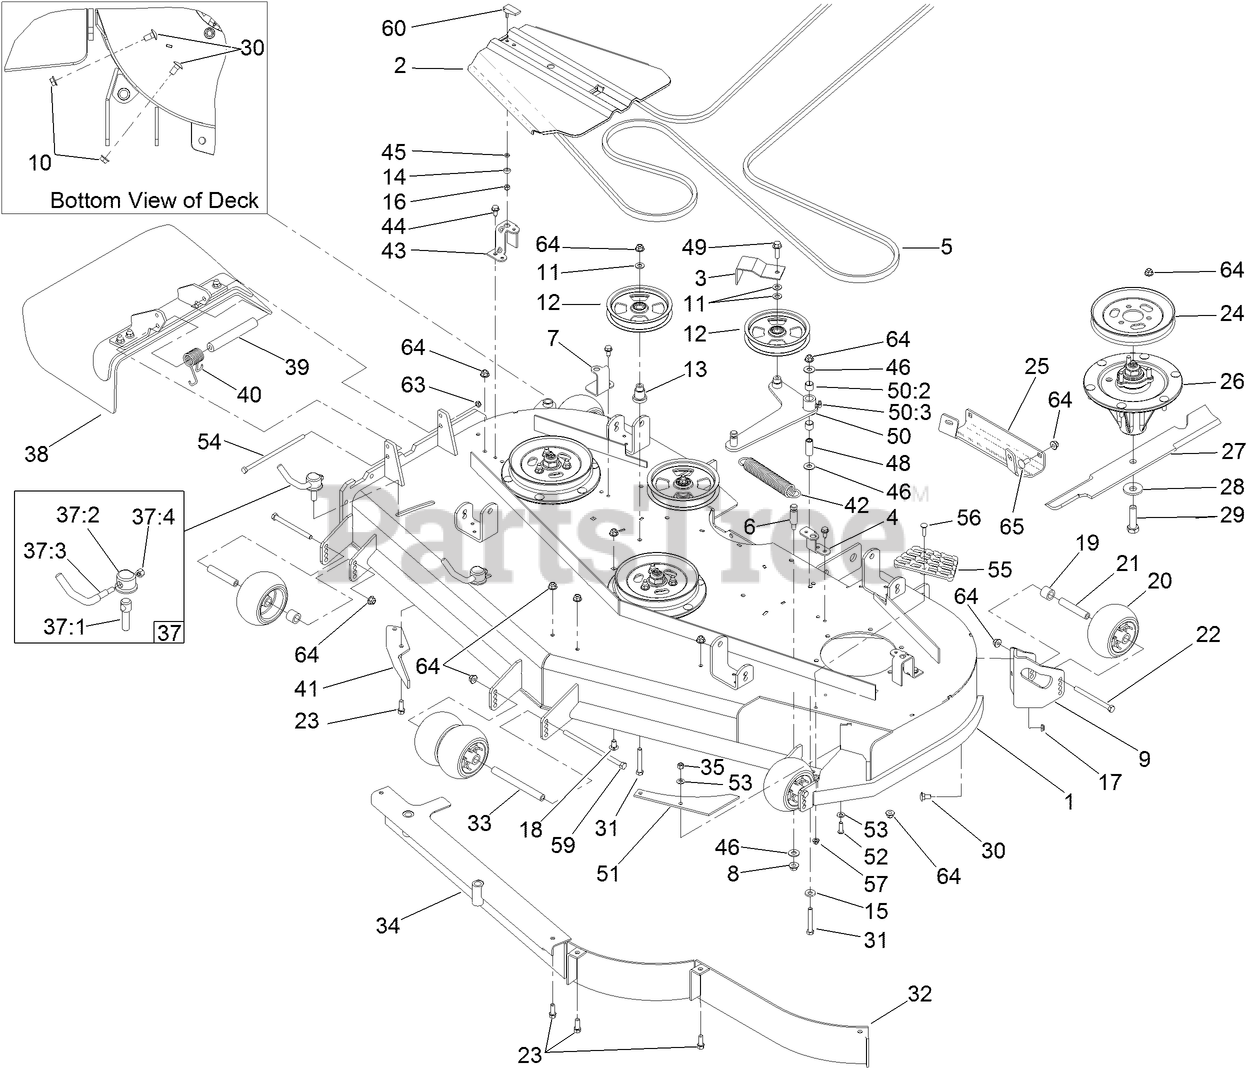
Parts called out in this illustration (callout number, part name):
1	DECK DECAL ASM
2	COVER-BELT
3	GUIDE-BELT
4	BRACKET-COVER, TALL
5	BELT-V
6	PIN-THREADED, SPRING ANCHOR
7	BRACKET-COVER
8	NUT-HF
9	MOUNT-WHEEL, LH
10	NUT-HHF, WHIZ
11	WASHER-FLAT
12	PULLEY-IDLER, FLAT
13	MOUNT-PULLEY
14	BUSHING-LATCH, SWELL
15	WASHER-BELLEVILLE
16	NUT-LOCK, HH
18	SCREW-CARR
19	TUBE-SPACER
20	ROLLER-SCALP, ANTI
21	TUBE-SPANNER
22	SCREW-HH
24	PULLEY
25	PLATE-SKID
26	SPINDLE ASM
27	BLADE-HI FLOW
28	WASHER-BLADE BOLT, HEAVY
29	SCREW-BLADE
30	SCREW-HH
31	SCREW-HH
33	SPACER-WHEEL
34	BAFFLE ASM
35	NUT-LOCK, NI
37	LEVER ASM
37:1	SCREW-LOCK
37:2	CAP-LOCK
37:4	NUT-LOCK, NI
38	RUBBER DEFLECTOR ASM
39	SPACER
40	SPRING-TORSION
41	BAFFLE-DISCHARGE
42	SPRING-EXTENSION
43	BRACKET-COVER
44	SCREW-HWHTF
45	WASHER
46	WASHER-FLAT
48	BUSHING
49	SCREW-HHF
50	DECK IDLER ARM ASM
50:2	SLEEVE-BEARING
50:3	FITTING-GREASE, 90 DEG
51	PLATE-TURBO
52	SCREW-HSBH
53	WASHER-SPRING
54	SCREW-HH
55	STEP-DECK
56	SCREW-CARR
57	NUT-HF, NI
59	SCREW-HH
60	HANDLE-LATCH, SWELL
63	NUT-LOCK, NI
64	NUT-HF, NI
65	SCREW-CARR
